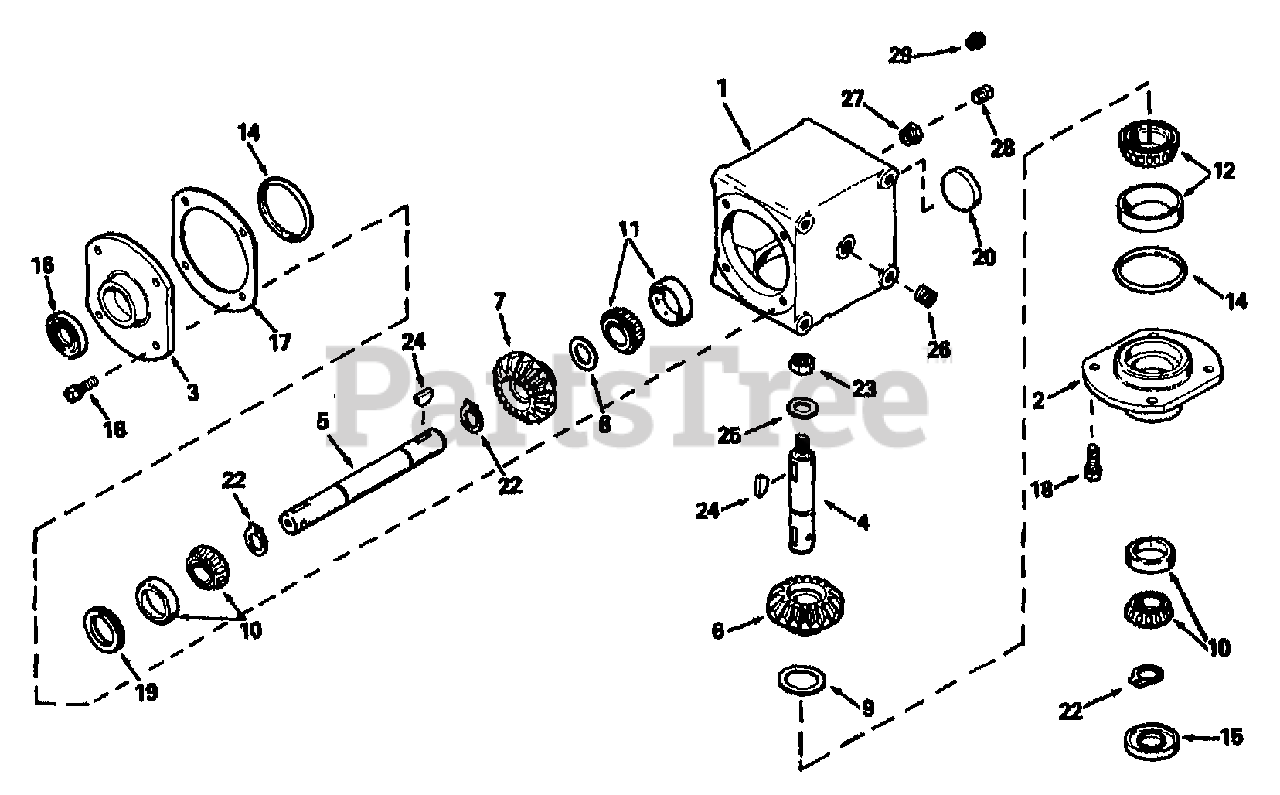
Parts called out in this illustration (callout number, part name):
1	Right Angle Drive Housing
2	Retainer Cap
3	Retainer Cap
4	Output Shaft
5	Input Shaft
6	Bevel Gear (20 teeth)
7	Bevel Gear (27 teeth)
8	Shim, 1-1/2" O.D. x 1-1/64 I.D. x .002 thick
9	Shim, 2.000" O.D. x 1.531 I.D. x .002 thick
10	Bearing & Cup Ass'y
11	Bearing & Cup Ass'y
12	Bearing & Cup Ass'y
14	"O" Ring
15	Oil Seal
16	Oil Seal
17	Cap Retainer Shim
19	Load Ring
20	Plug
22	Retaining Ring
24	Woodruff Key
25	Flat Washer
28	Pipe Plug
29	Relief Valve
